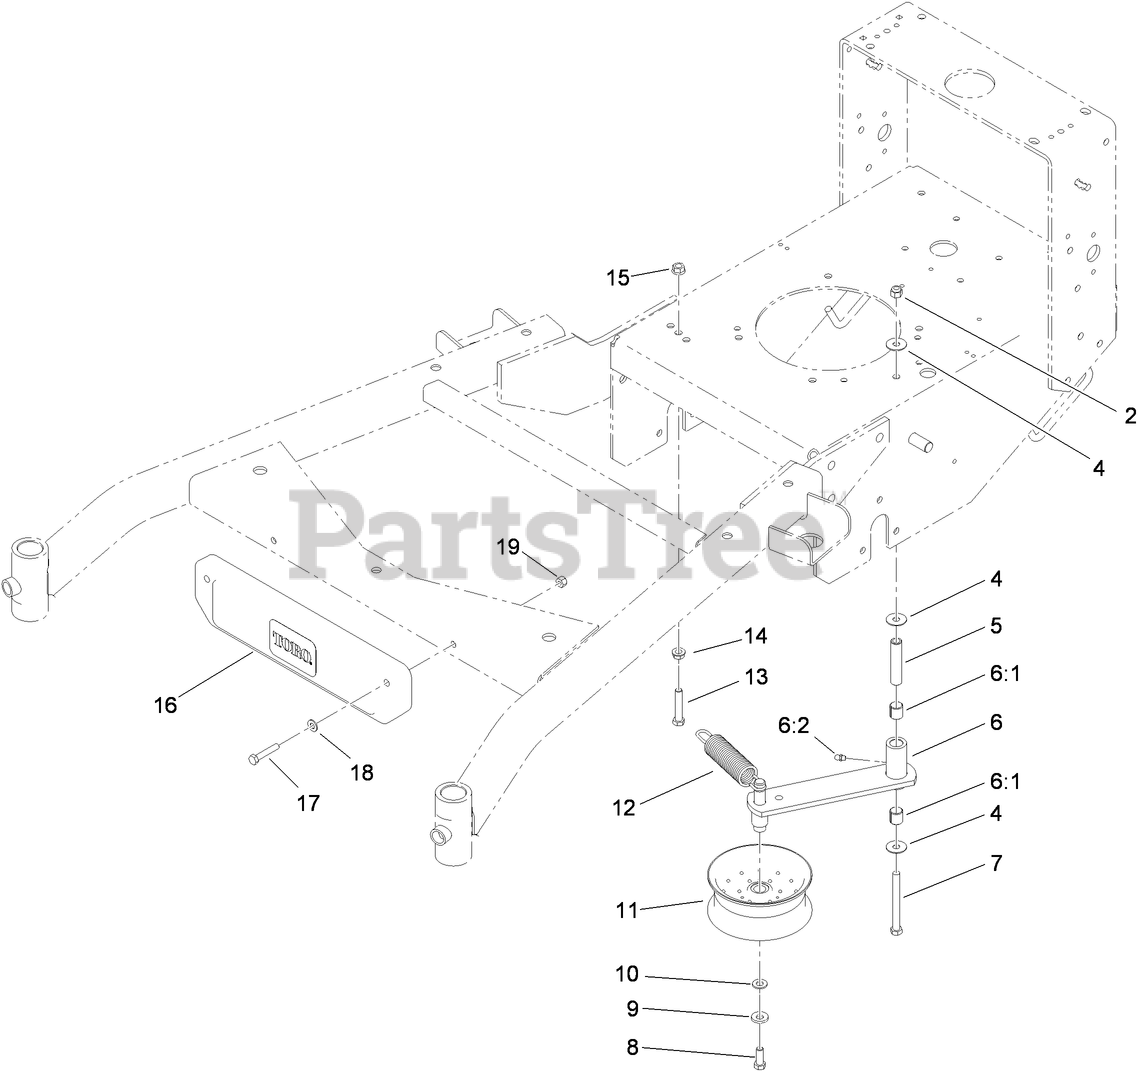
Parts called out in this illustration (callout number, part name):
2	NUT-LOCK, NI
4	WASHER
5	TUBE-IDLER
6	IDLER ARM ASM
6:1	SLEEVE-BEARING
6:2	FITTING-GREASE
7	SCREW-HH
8	SCREW-HH
9	WASHER-BELLEVILLE
10	WASHER-FLAT
11	PULLEY-IDLER
12	SPRING-EXTENSION
13	SCREW-HH
14	NUT-HHF, WHIZ
15	NUT-HF
16	WEIGHT-CAST
17	SCREW-HH
18	WASHER-PLAIN
19	NUT-LOCK, NI
